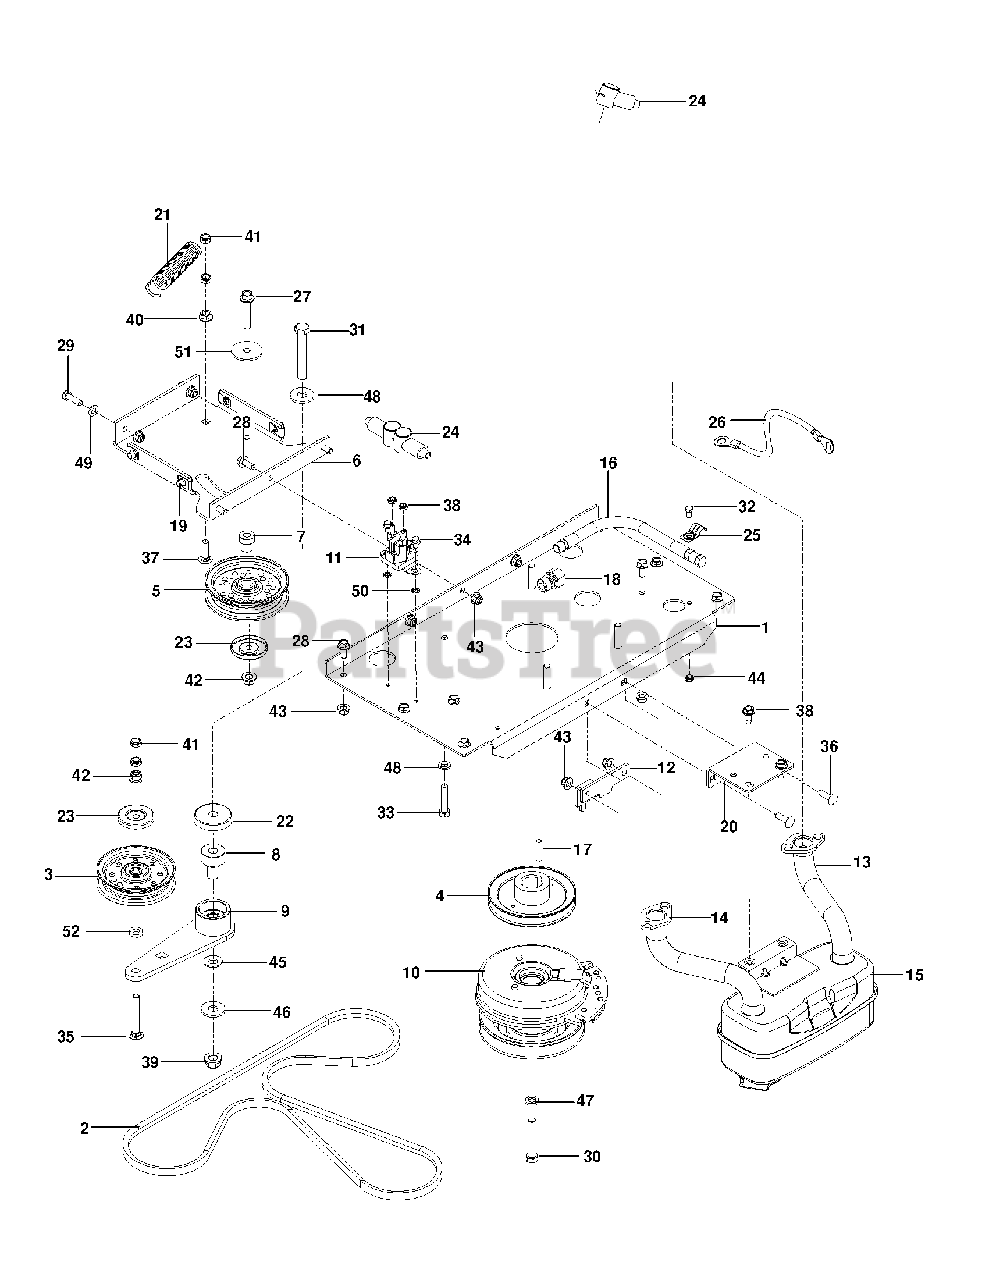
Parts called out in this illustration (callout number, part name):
1	PLATE, ENGINE W/DECALS
2	BELT, HYDRO, 3400
3	PULLEY.IDLER.FLAT.46.PR.DR.
4	PULLEY, V, 1.125 BORE
5	IDLER PULLEY
6	PLATE, IDLER, BLK
7	PIVOT, IDLER
8	PIVOT, BEARING
9	ARM, IDLER, STEEL, W/BGS
10	CLUTCH 200 FT LB
12	STOP, CLUTCH, BLACK
13	TUBE.EXHAUST.LH.FR961/FR730
14	TUBE.EXHAUST.RH.FR961/FR730
15	MUFFLER ASM TWIN
16	HOSE.ASSEMBLY.OIL.DRAIN
17	KEY, 1/4 SQ X 1 1/4
18	ADAPTER, OIL DRAIN
19	U-CLIP 5/16-18 NUT RETAINER
20	BRKT, MUFFLER, BLK
21	SPRING, PUMP
22	SHIELD, DUST
23	DUST SHIELD
26	CABLE POSITIVE
27	HHFS 3/8-16 X 2.0 GD 5
28	HHFS 5/16-18 X 3/4
29	HCS 5/16C X 1
30	CLUTCH BOLT7/16-20X2.5 GR596HR
31	HCS 1/2C X 3 1/4
32	HCS 1/4-20.
33	BOLT, HCS 3/8-16X1-3/4
34	HWST 1/4C X 3/8
35	RHSNB 3/8-16 X 2.75
36	RHSSNB 5/16C X 1.0
37	RHSNB 3/8-16 X 1-1/4
38	BOLT 5/16-18 X 3/4
39	NUT, 1/2-13 HEX FLG NYLOC ZD
40	NUT 3/8C WHIZ
41	NUT HEX 3/8-16 NYLON, THIN
42	NUT 3/8-16 HEX FLG NYLOC ZD
43	5/16-18 NYLOC FLANGE NUT
44	JAM NUT 1/4C (2 2 PW01)
45	CONTACT BELLSPR 1/2
46	WASH USS FLAT 1/2
47	WASHER 7/16 LOCK
48	SLW 3/8 STD
49	FLAT WASHER 5/16 SAE
50	WASHER 1/4 INT TOOTH
51	WASHER, 3/8 SPEC
52	WASHER 3/8 X 3/4 X .187 TK
